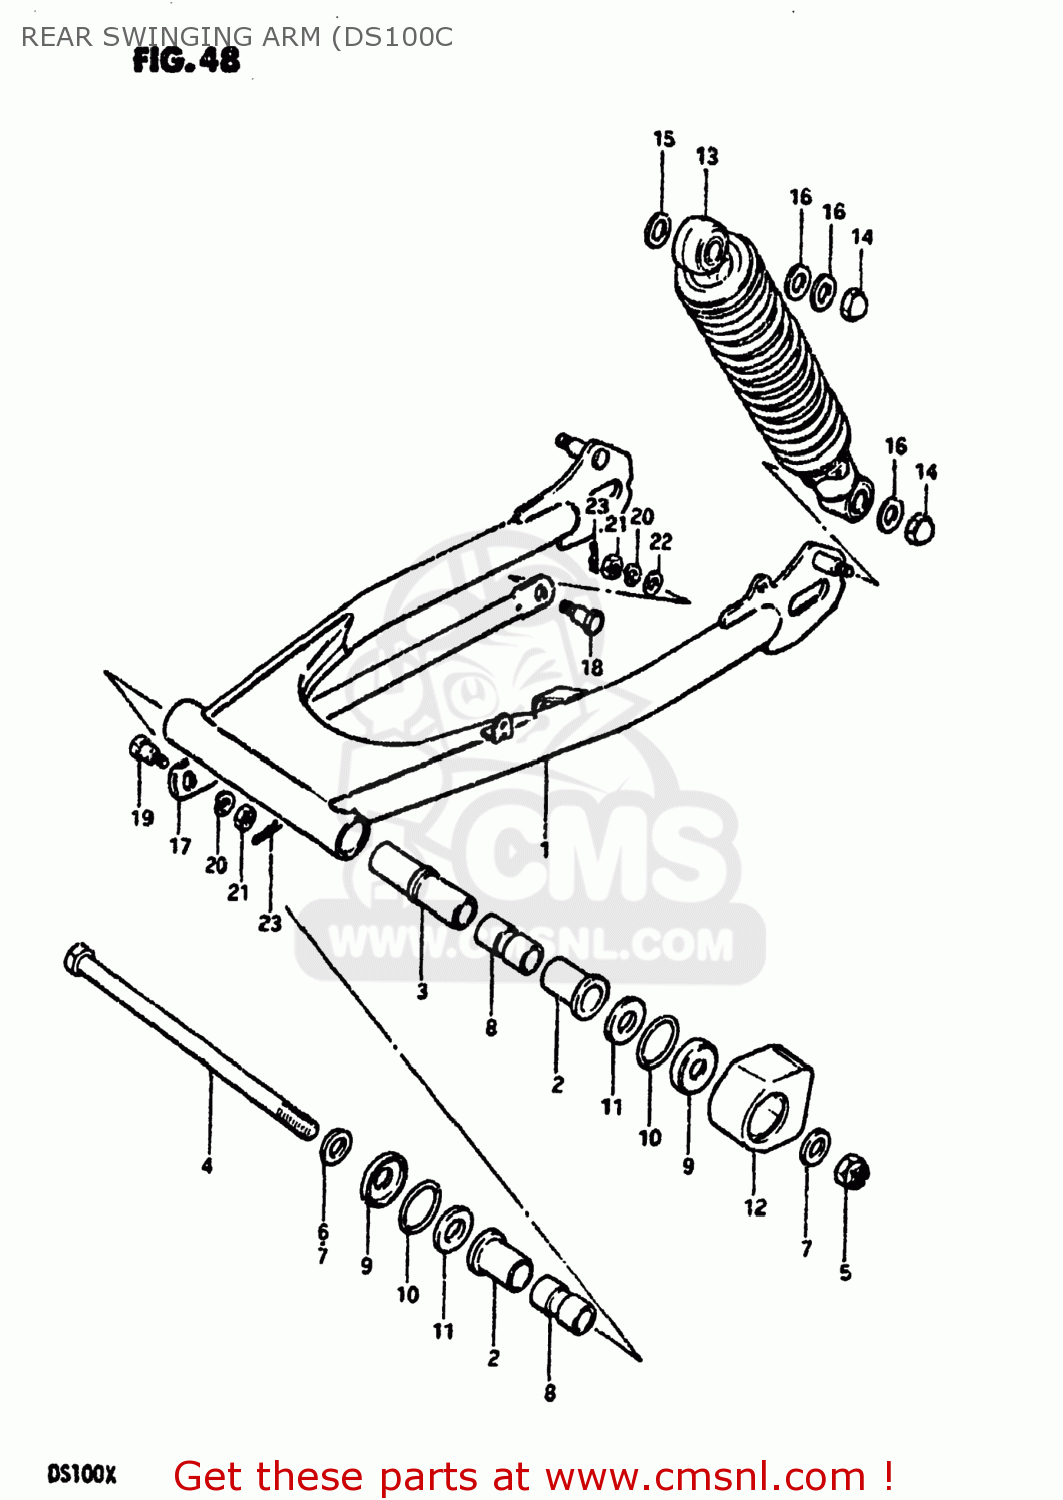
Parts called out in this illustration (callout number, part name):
1	SWING ARM ASSEMBLY,REAR
2	BUSH
3	SPACER,RR SWGARM PIVOT CTR
4	SHAFT,REAR SWING ARM
5	NUT
6	WASHER
7	WASHER
8	SPACER,RR SWGARM PIVOT
9	COVER,SWGARM BUSH DUST SEAL
10	O RING(D:2,ID:24.5)
11	WASHER(12.5X24X2.3)
12	BUFFER,CHAIN TOUCH DEFENSE
13	ABSORBER ASSEMBLY,REAR SHOCK
14	NUT, LOWER LH
15	WASHER
16	WASHER
17	TORQUE LINK,REAR
18	BOLT(8X22)
19	BOLT(8X26.5)
20	LOCK WASHER
21	NUT
22	WASHER
23	CLIP
